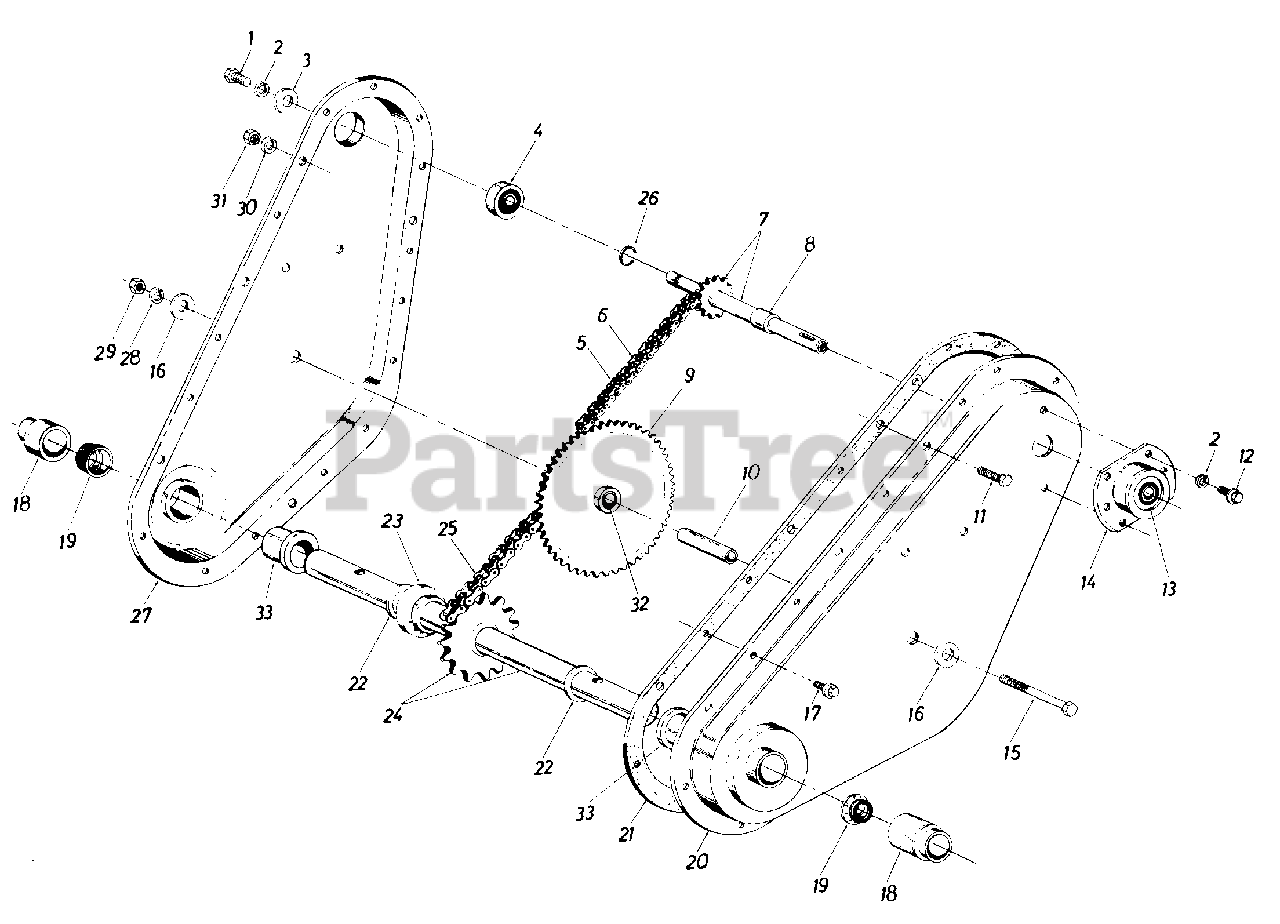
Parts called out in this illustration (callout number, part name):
1	Hex L-Scr. 1/4-28 x .625" Lg.
2	L-Wash. 1/4" I.D.
3	Fl-Wash. .25" I.D. x .93" O.D. x .125" Thk.
4	Bearing .62" I.D. x 1.38" O.D. x .437" Thk.
5	#35 Chain 318" Pitch x 52 0 Links-Endless
6	Master Link
7	Input Shaft Assembly
8	Spacer
9	Sprocket Assembly
10	Sprocket Hub Tubing 318" I.D. x 5/8" O.D. x 1.9" Lg.
11	Hex Scr. 5/16-18 x .625" Lg.
12	Hex Wash. Hd. Self-Tap Scr. 1/4-20 x .50" Lg.
13	Bearing .625" I.D. x 1.38" O.D. x .437" Thk.
14	Bearing Housing
15	Hex Scr. 3/8-24 x 2.75" Lg.
16	Fl-Wash. 318" I.D. x 1.25" O.D. x .100 Thk.
17	Hex Wash. Hd. Self-Tap Scr. 1/4-20 x .50" Lg.
18	Dust Cap
22	Thrust Wash. 1.00" I.D. x .030" Thk.
23	Step Spacer
24	Tine Shaft Assembly
25	#50 Chain 5/8" Pitch x 46 0 Links-Endless
26	Snap Ring
29	Hex Nut 3/8-24 Thd.
30	L-Wash. 5/16" Scr.
31	Hex Nut 5/16-18 Thd.
32	Bearing
33	Bearing
